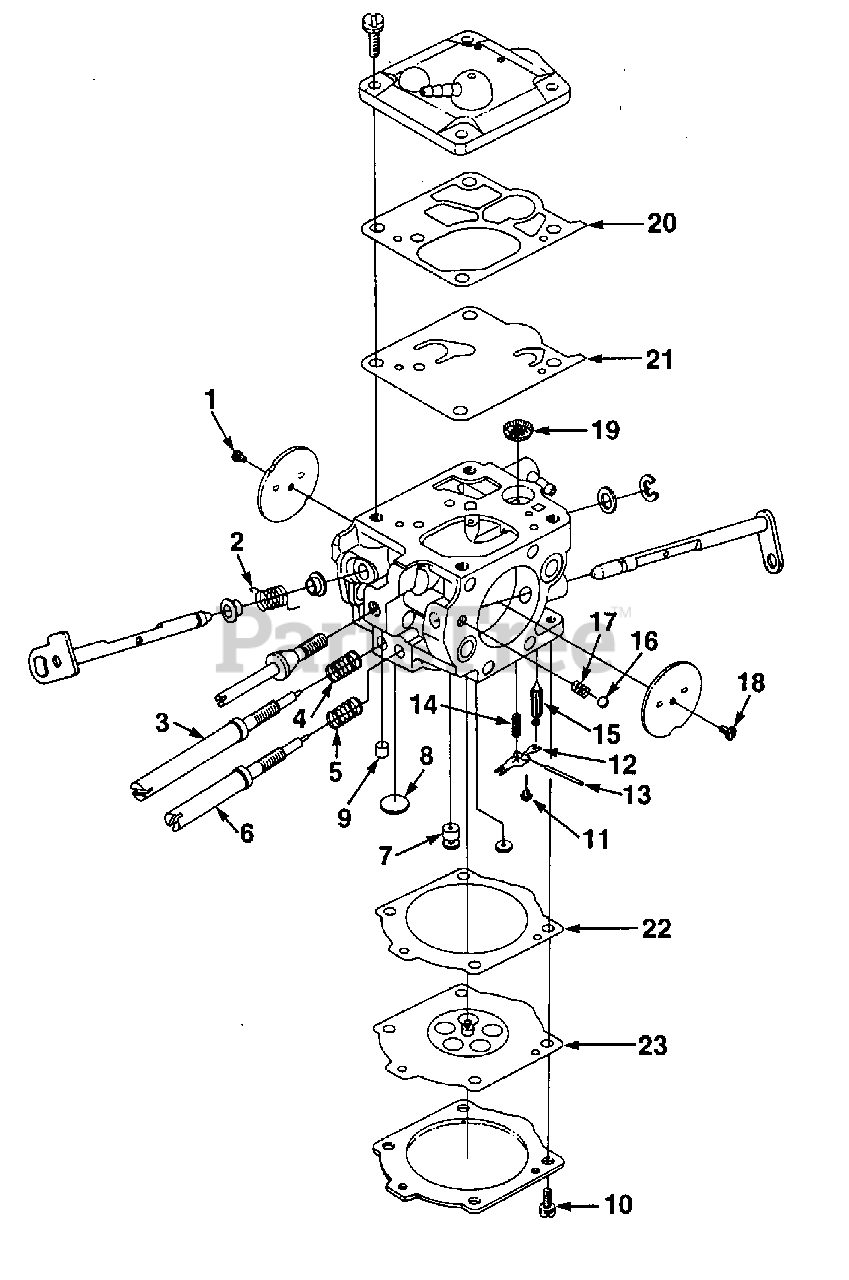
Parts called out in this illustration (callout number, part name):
1	Repair Kit (Includes 1-23)
2	Repair Kit (Includes 1-23)
3	Repair Kit (Includes 1-23)
4	Repair Kit (Includes 1-23)
5	Repair Kit (Includes 1-23)
6	Repair Kit (Includes 1-23)
7	Repair Kit (Includes 1-23)
8	Repair Kit (Includes 1-23)
9	Repair Kit (Includes 1-23)
10	Repair Kit (Includes 1-23)
11	Repair Kit (Includes 1-23)
12	Repair Kit (Includes 1-23)
13	Repair Kit (Includes 1-23)
14	Repair Kit (Includes 1-23)
15	Repair Kit (Includes 1-23)
16	Repair Kit (Includes 1-23)
17	Repair Kit (Includes 1-23)
18	Repair Kit (Includes 1-23)
19	Repair Kit (Includes 1-23)
20	Repair Kit (Includes 1-23)
21	Repair Kit (Includes 1-23)
22	Repair Kit (Includes 1-23)
23	Repair Kit (Includes 1-23)
